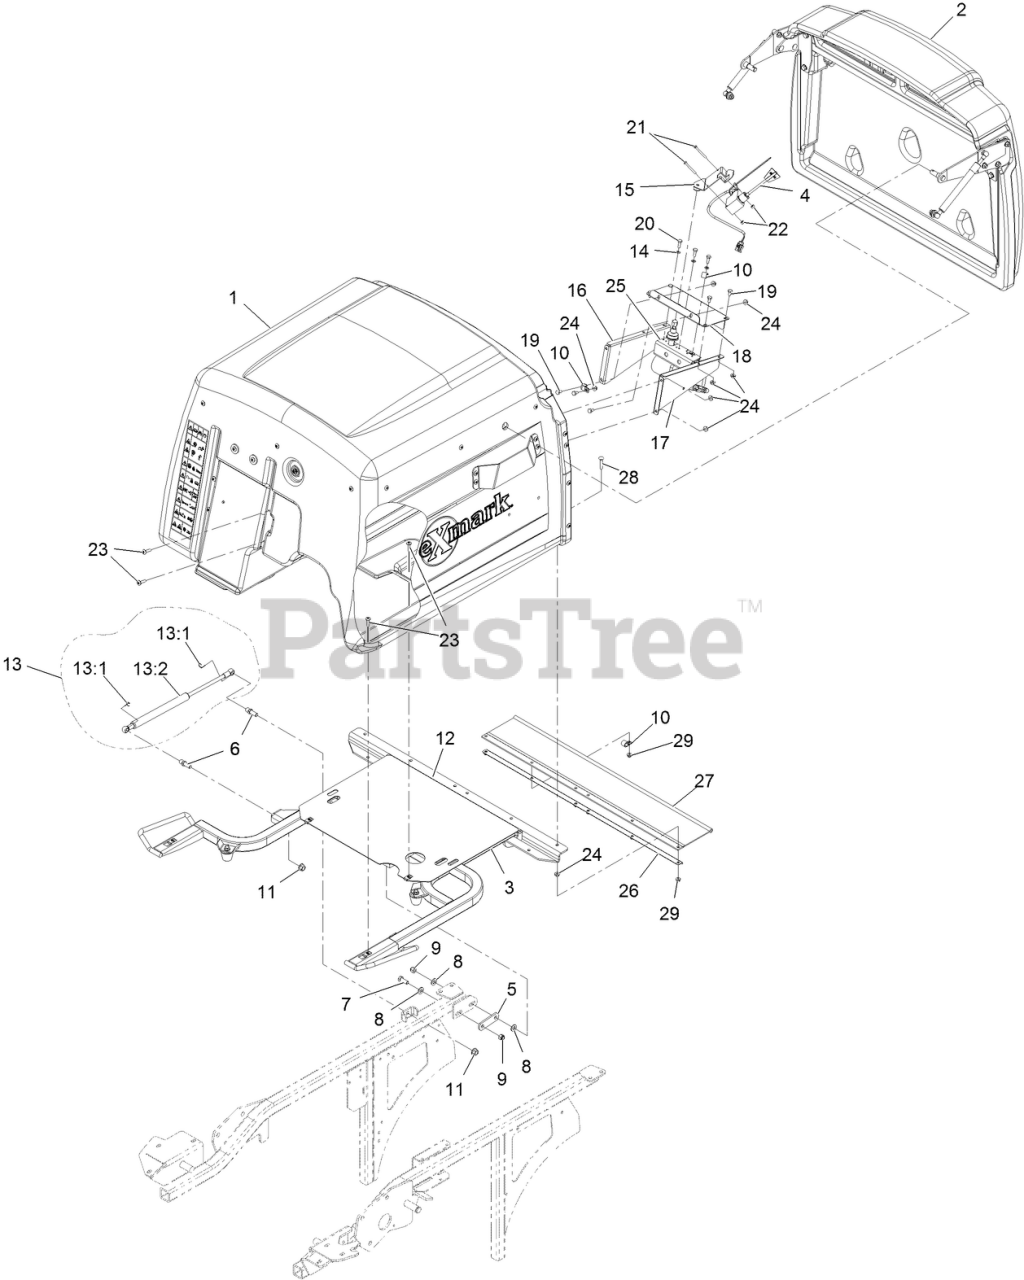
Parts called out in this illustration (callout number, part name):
1	ASM,HOPPER
1	HOPPER ASM
2	ASM,DOOR HOPPER
3	HOPPER FRAME ASM
4	FILL SENSOR ASM
5	ARM-LIFT, DECK
6	STUD-BALL
7	SCREW-HH
8	WASHER-FLAT
9	NUT-LOCK, NI
10	CLIP-LOOM
12	SCREW-SHOULDER, HWH
13	DAMPER KIT
13:1	CLIP-RETAINER
13:2	SHOCK-COMPRESSION, GAS
14	WASHER-SPRING
15	MOUNT-SWITCH
16	BRACKET-DRIVE MOTOR, LH
17	BRACKET-DRIVE MOTOR, RH
18	PLATE-SWITCH
19	SCREW-HH
20	SCREW-HH
21	SCREW-PPH
22	NUT-LOCK, NI
23	SCREW-TTH
25	KIT,FILL SENSOR MOTOR
26	CHANNEL-FRAME, HOPPER
27	DEFLECTOR-GRASS
28	SCREW-CARR
